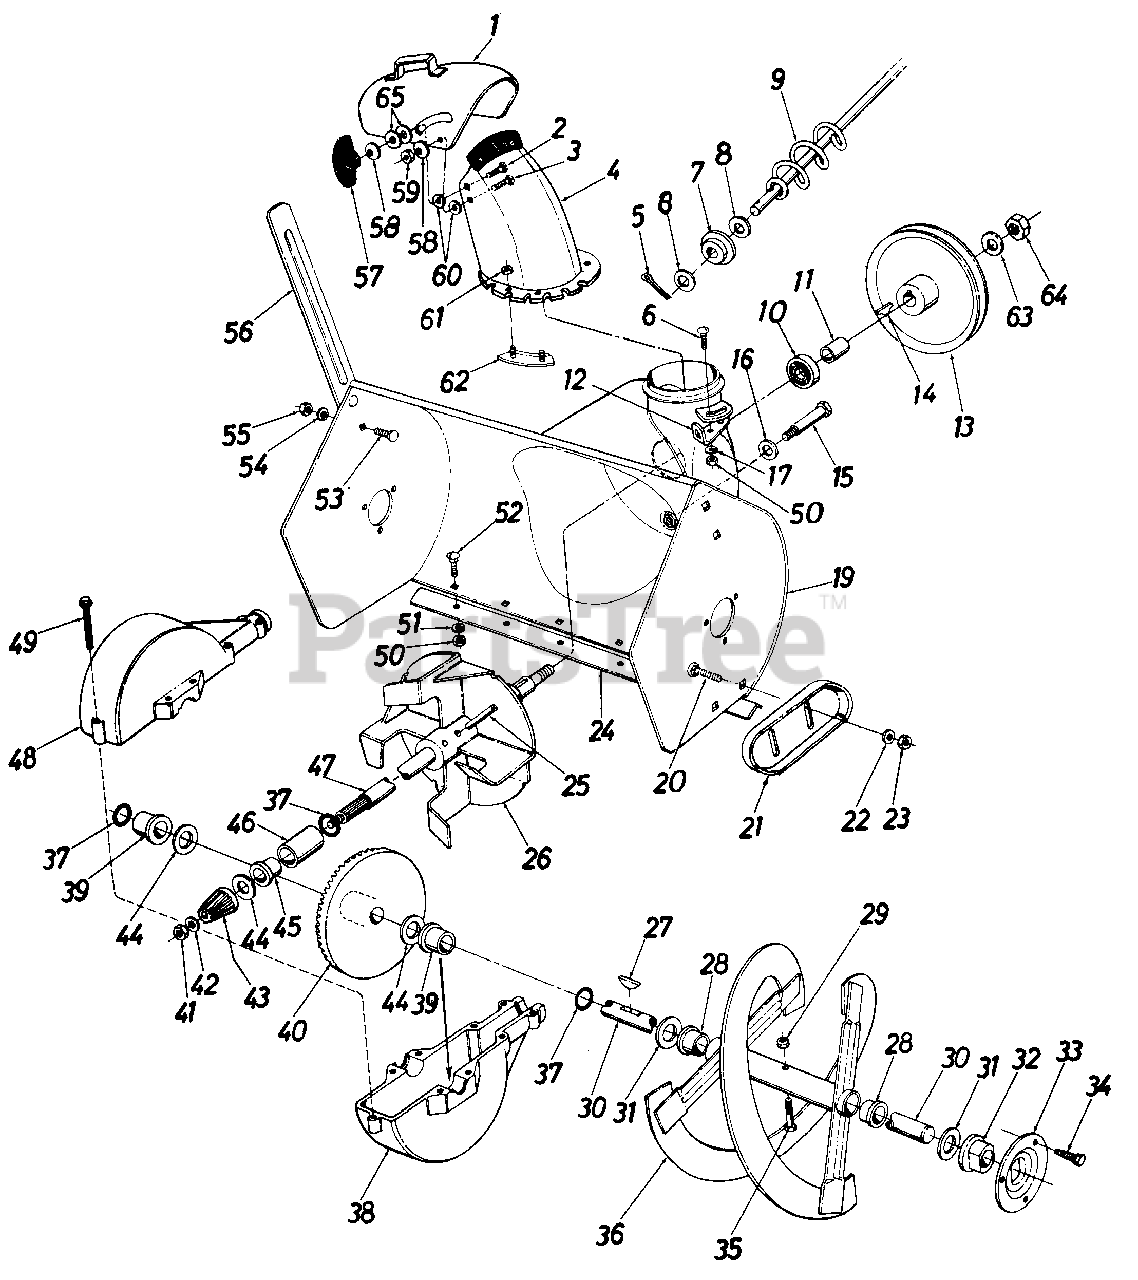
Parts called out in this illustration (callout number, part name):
1	Top Chute Ass'y.
2	Carriage Bolt 5/16-18 x 1.00" Lg.*
3	Carriage Bolt 5/16-18 x .62" Lg.*
4	Chute Ass'y.
5	Cotter Pin
6	Carriage Bolt 5/16-18 x .75" Lg.*
7	Hex Bushing
8	Fl-Wash. 385 I.D. x .62" O.D.
9	Chute Crank Ass'y.
10	Ball Brg. .62" I.D. x 1.38" O.D.
11	Spacer.63" I.D. x .88" O.D. x .900" Lg.
13	1/2" "V"-Pulley .625" I.D. x 7.50" O.D.
14	#61 Hi-Pro Key 3116" x 518" Dia.
15	Shld. Bolt .50" Dia. x 2.11" Lg.
16	Bell-Wash. .40" I.D. x .88" O.D. x .06
17	Bell-Wash. .34" I.D. x .88" O.D.
20	Carriage Bolt 3/8-16 x .62" Lg.*
21	Slide Shoe
22	Bell-Wash. 3/8" I.D.
23	Hex Jam Nut 3/8-16 Thd.
24	20" Shave Plate
26	11" Dia. Blower Fan Ass'y.
27	#9 Hi-Pro Key 3/16 x 314" Dia.
28	Flange Brg. .75" I.D. x .88" O.D. x .62
29	Hex Ins. L-Nut 5/16-18
30	Spiral Axle
31	Fl-Wash. .75" I.D. x 1.50" O.D. x .06
32	Flange Brg. w/Flats .755" I .D.
33	Bearing Housing
34	Hex Wash. Hd. Self-Tap Scr. 5/16-24 x .50" Lg.
35	Hex Bolt 5/16-18 x 1.50" Lg.
36	20" Spiral Ass'y.-L.H.
37	"O"-Ring-314" I.D.
38	Bevel Gear Housing-Lower Half
39	Plastic Flange Brg. .755" I.D.
40	Bevel Gear
41	Hex Cent. L-Nut 5/16-24 Thd.
42	Fl-Wash. .34" I.D. x .62" O.D. x .06
43	Pinion Gear
44	Fl-Wash. .75" I.D. x 1.25" O.D. x .06
45	Flange Brg. .755" I.D.
46	Sleeve Brg. .755" I.D.
47	Blower Axle
48	Bevel Gear Housing- [Upper Half
49	Hex Wash. Hd. Self-Tap Scr. 1/4-20 x 1.00" Lg.
50	Hex Nut 5/16-18 Thd.
51	Bell-Wash. .34" I.D. x .88" O.D.
52	Carriage Bolt 5/16-18 x .62" Lg.*
53	Carriage Bolt 5/16-18 x .62" Lg.*
54	L-Wash. 5/16" I.D.
55	Hex Nut 5/16-18 Thd.
56	Drift Cutter Bar
57	Knob
58	Bell-Wash. .34" I.D. x .88" O.D.
59	Hex Cent. L-Nut 5/16-18 Thd.
60	Fl-Wash. .53" I.D. x 1.25" O.D. x .100
61	Hex Cent. L-Nut 1/4-20 Thd.
62	Chute Flange Keeper Ass'y.
63	Fl-Wash. .64" I.D. x .94" O.D. x .06
64	Hex Jam Nut 5/8-18 Thd.
65	Fl-Wash. .344 I.D. x 1.125 O.D.
